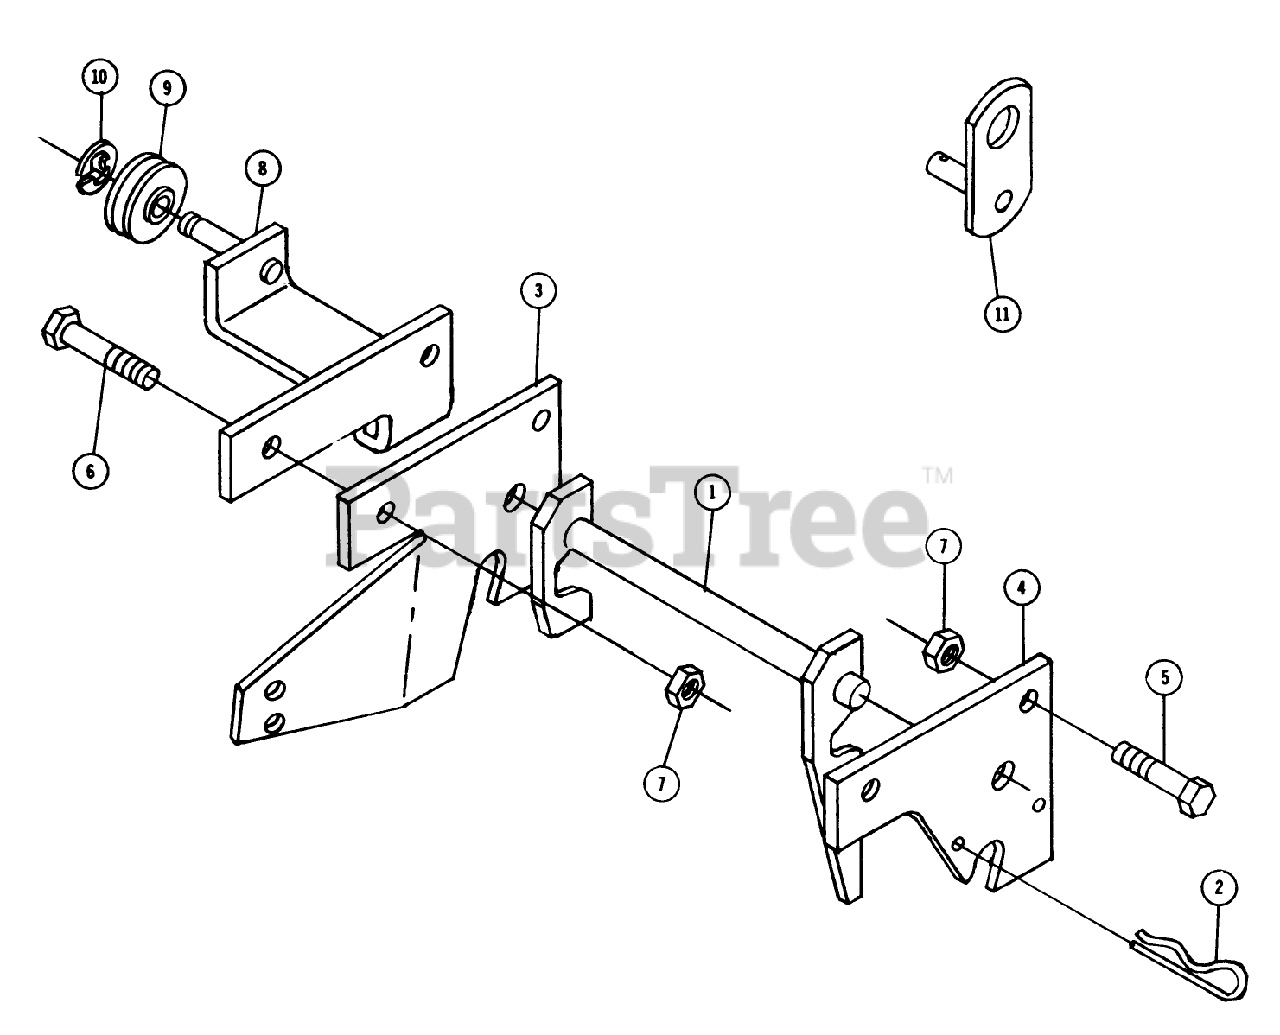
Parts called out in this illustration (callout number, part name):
1	ASSY LATCH & SHAF R
2	Hairpin
3	MOUNTING BRACKET R
4	PLATE-MTG BRKT LH R (NS)
5	Bolt 3/8-16 x 1
6	Bolt 3/8-16 x 1
7	3/8-16 E.S.
8	ASSY BRACKET AND R
9	ROLLER
10	Lock Rod
11	Cam Arm
